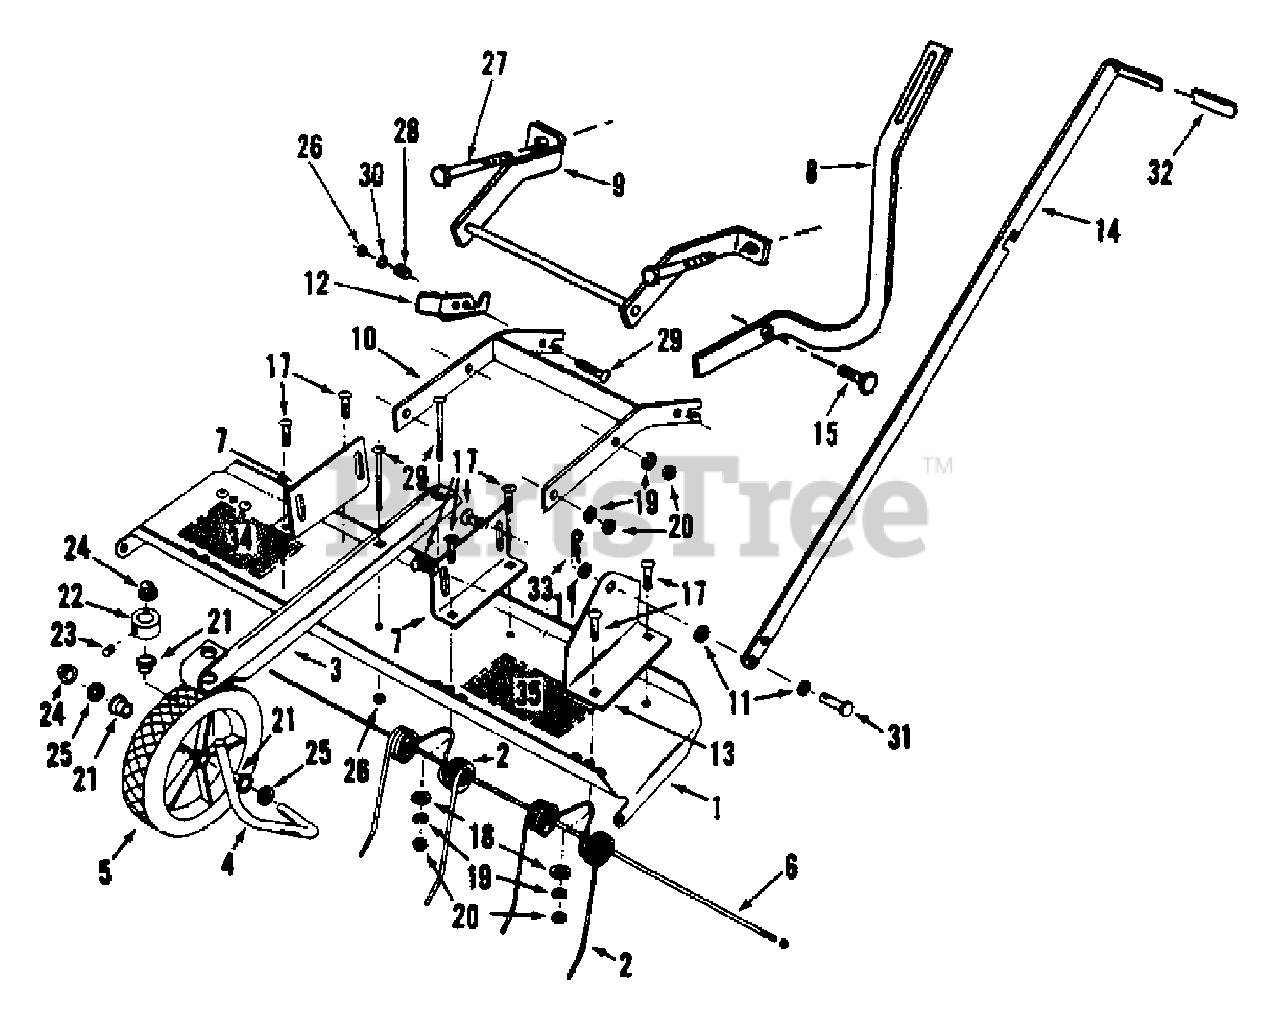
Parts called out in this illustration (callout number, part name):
1	TRAY, Tine
2	TINE, Thatching
3	SUPPORT, Wheel
4	AXLE
5	WHEEL, Gauge
6	ROD, Tine
7	BRACKET, Frame Mounting
8	SUPPORT, Lift Handle
9	WELDMENT, Hitch Bar
10	ASSEMBLY, Main Frame Weldment
11	WASHER, 5/16 SAE Flat
12	LATCH, Frame Mount
13	BRACKET, Lift
14	HANDLE, Lift
15	SCREW, 5/16-18 x 1" Hex Head Cap, Grade 5
16	BOLT, 1/4-20 x 2-1/2" Square Neck Carriage
17	BOLT, 5/16-18 x 1" Square Neck Carriage, Grade 5
18	WASHER, Reinforcing
19	WASHER, 5/16" Split Lock
20	NUT, 5/16-18 Hex, Grade 5
21	BEARING, Nyliner
22	BUSHING, Wheel Adjustment
23	SCREW, 5/16-18 x 1/4" Set
24	NUT, 1/2" Push
25	WASHER, 1/2" SAE Flat
26	NUT, 1/4-20 Hex Top Lock
27	SCREW, 5/16-18 x 2-1/2" Hex Head Cap, Grade 5
28	SPRING, Compression
29	BOLT, 1/4-20 x 1-1/4" Square Neck Carriage, Grade 5
30	WASHER, 1/4" SAE Flat
31	PIN, 5/16" Lift
32	GRIP, Handle
33	COTTER, Hairpin
34	DECAL, Thatcherizer
35	DECAL, Adjustment
